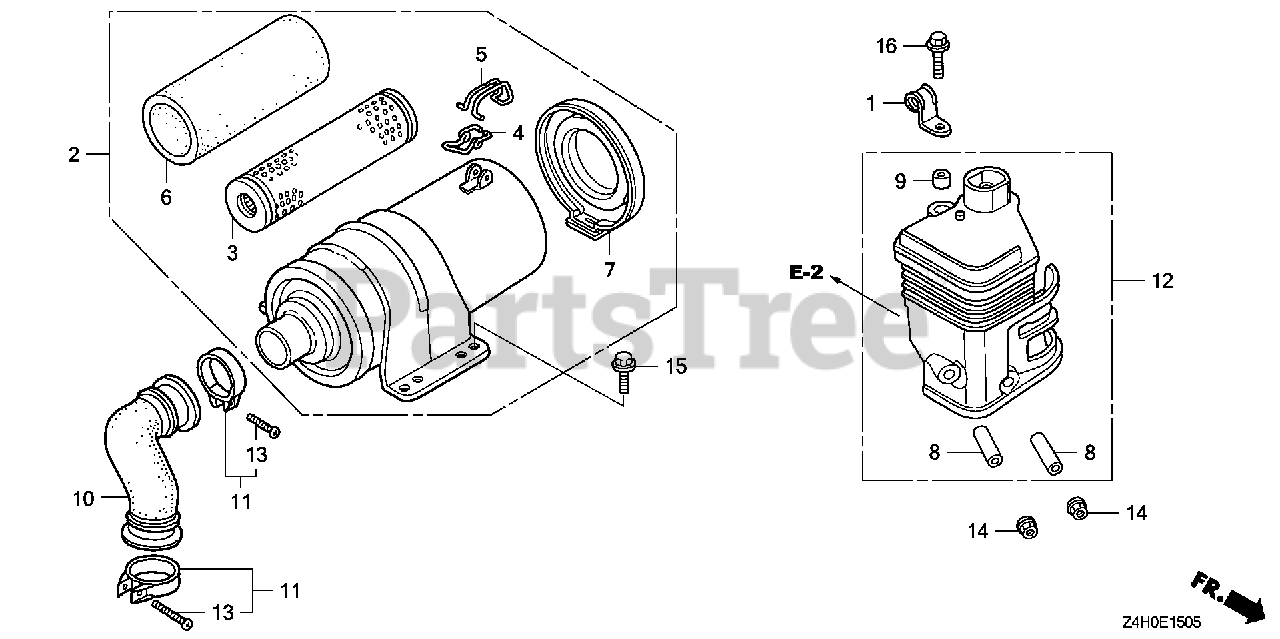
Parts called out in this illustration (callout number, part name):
1	CLIP B, TUBE
8	COLLAR, AIR CLEANER Use from Engine SN 1786085.
9	COLLAR B, AIR CLEANER
12	ELBOW, AIR CLEANER
14	NUT, FLANGE (6MM)
16	BOLT, FLANGE (6X20)
